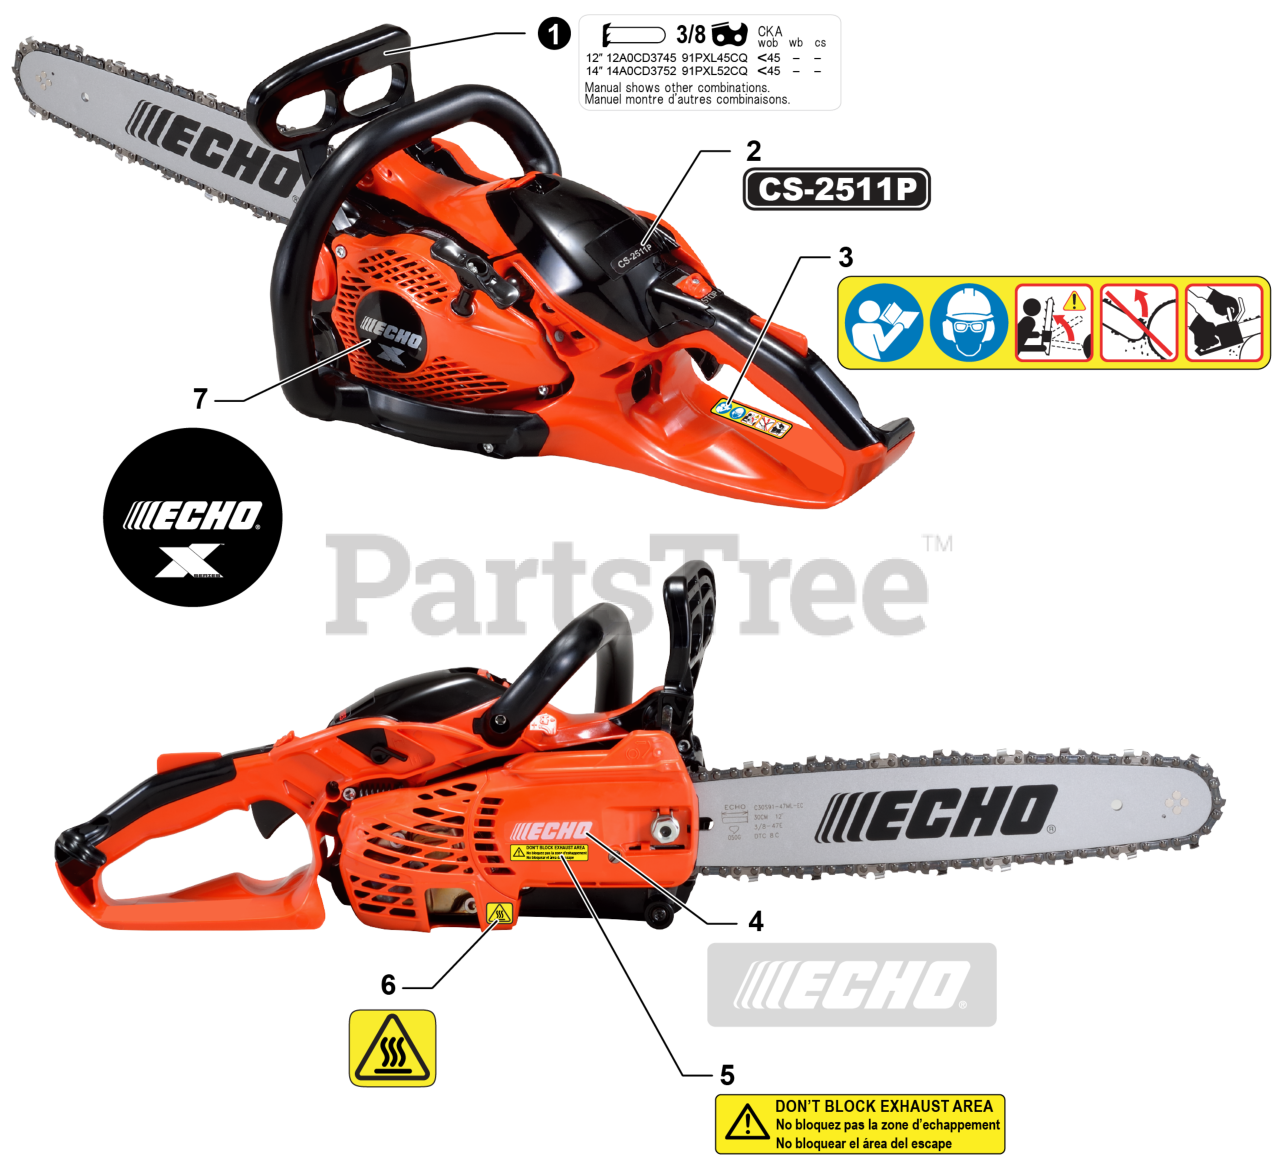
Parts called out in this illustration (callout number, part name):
1	LABEL - BAR & CHAIN
2	LABEL - CS-2511P
3	LABEL - CAUTION
4	LABEL - ECHO
5	LABEL - CAUTION - DON'T BLOCK EXHAUST AREA
6	LABEL - CAUTION - HOT
7	LABEL - ECHO
